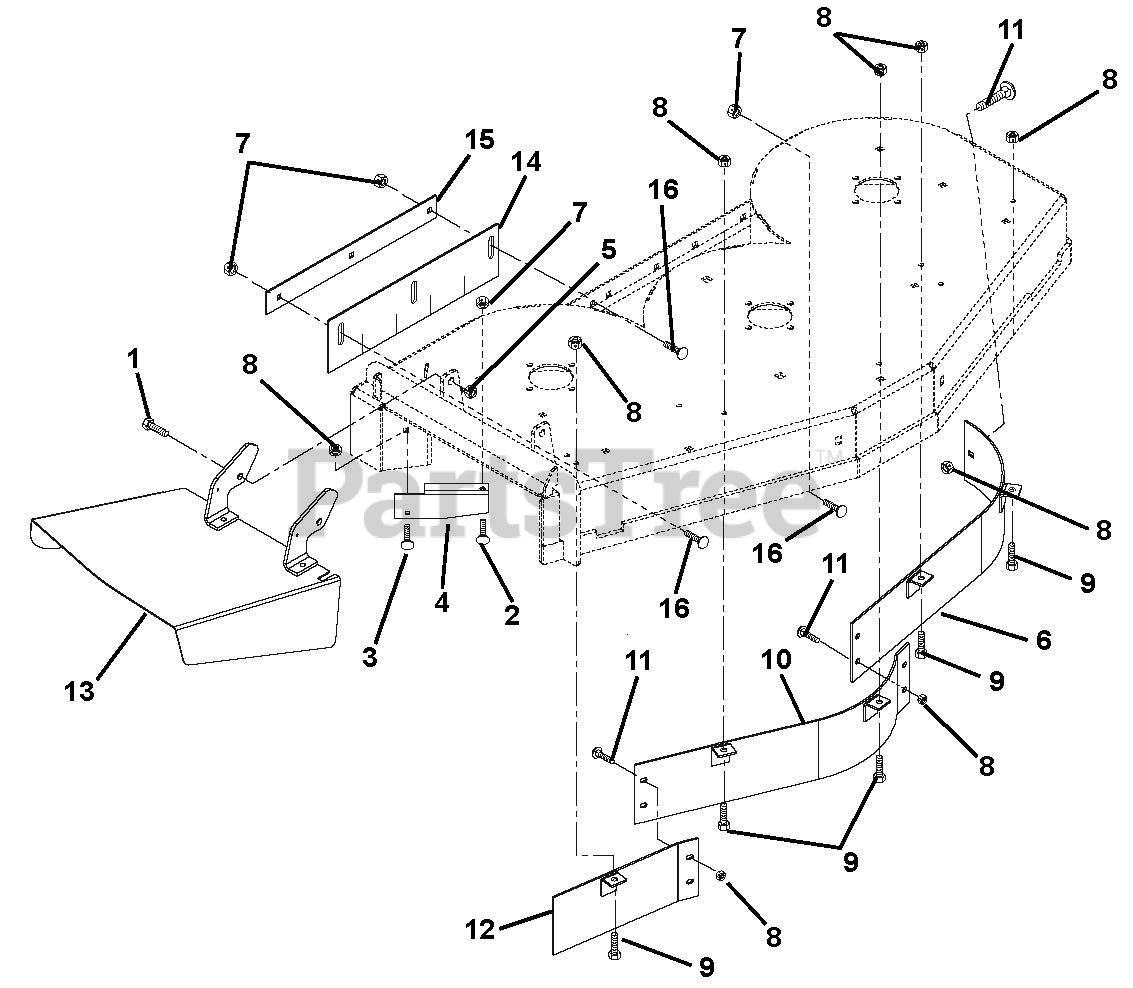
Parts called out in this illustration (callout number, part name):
1	Bolt-Hex .50-13 x 1.25 Grade 5
2	Bolt-Round Head Square Neck .38-16 x .75 Grade 5
3	Bolt-Round Head Square Neck .31-18 x 1.00 Grade 5
4	Deflector 44"/48"
5	Nut-Locking-Nylon .50-13
6	Weldment- Upper Baffle Left
6	Weldment- Baffle- Left Front-44"
7	Nut-Locking-Top-Flange .38-16
8	Nut-Locking-Top-Flange .31-18
9	Bolt-Hex .31-18 x .75 Grade 5
10	Weldment- Upper Baffle Center
10	Weldment-Baffle-Center Front- 44"
11	Bolt-Round Head Square Neck .31-18 x .75 Grade 5
12	Weldment, Right Hand Baffle-Upper
12	Weldment-Baffle-Right Front- 44"
13	Chute-Discharge
14	Skirt- Rubber
15	Strip- Striper Mount
16	Bolt-Round Head Square Neck .38-16 x 1.00 Grade 5
